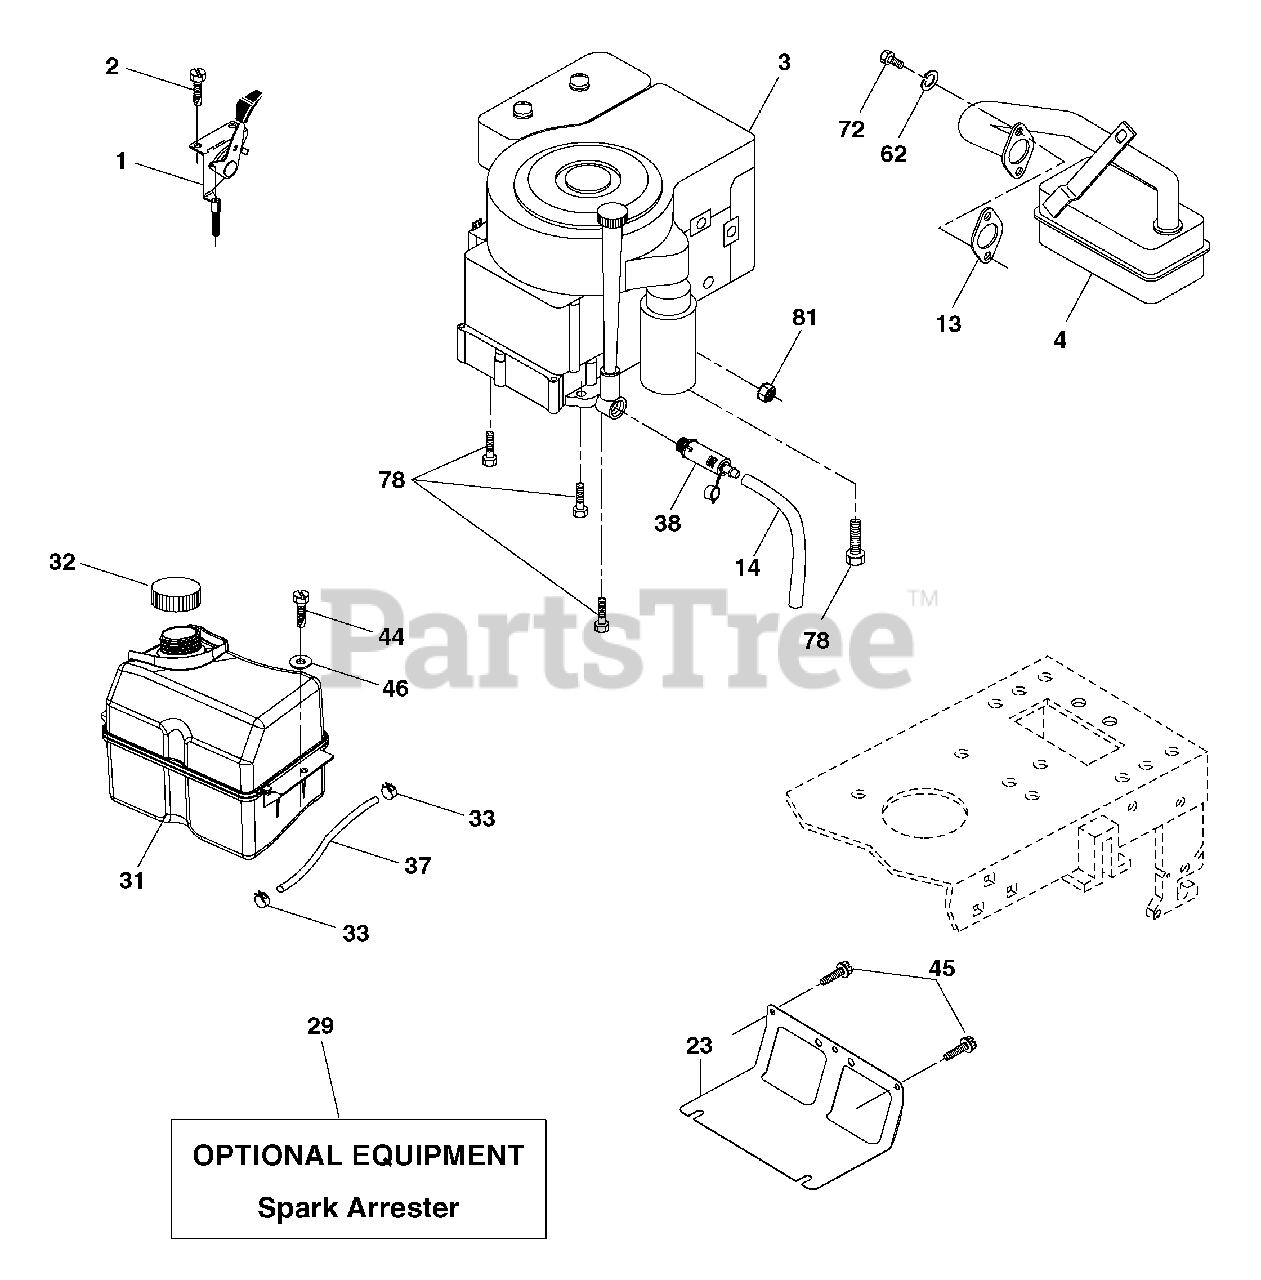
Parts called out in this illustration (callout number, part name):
1	Control, Throttle
2	Screw Hex Thd Cut 1/4-20 x 1/2
4	Muffler
13	Muffler Gasket
14	Tube Oil Drain
23	Shield, Browning/Debris Guard
29	Arrester, Spark
31	Tank, Fuel
32	Cap, Fuel
33	Clamp, Hose Blk
37	Line, Fuel
38	Plug Drain Oil Easy
44	Screw Hex Wsh Thdrol 1/4-20 x 3/4
45	Screw Hex Wsh Thdrol 3/8-16 x 3/4
46	Washer 9/32 x 7/8 x 16 Ga.
62	Washer Split
72	Screw Socket Hd 5/16-18 x .75
78	Screw 3/8-16 x 1-1/4
81	Nut Keps Hex 1/4-20 unc
